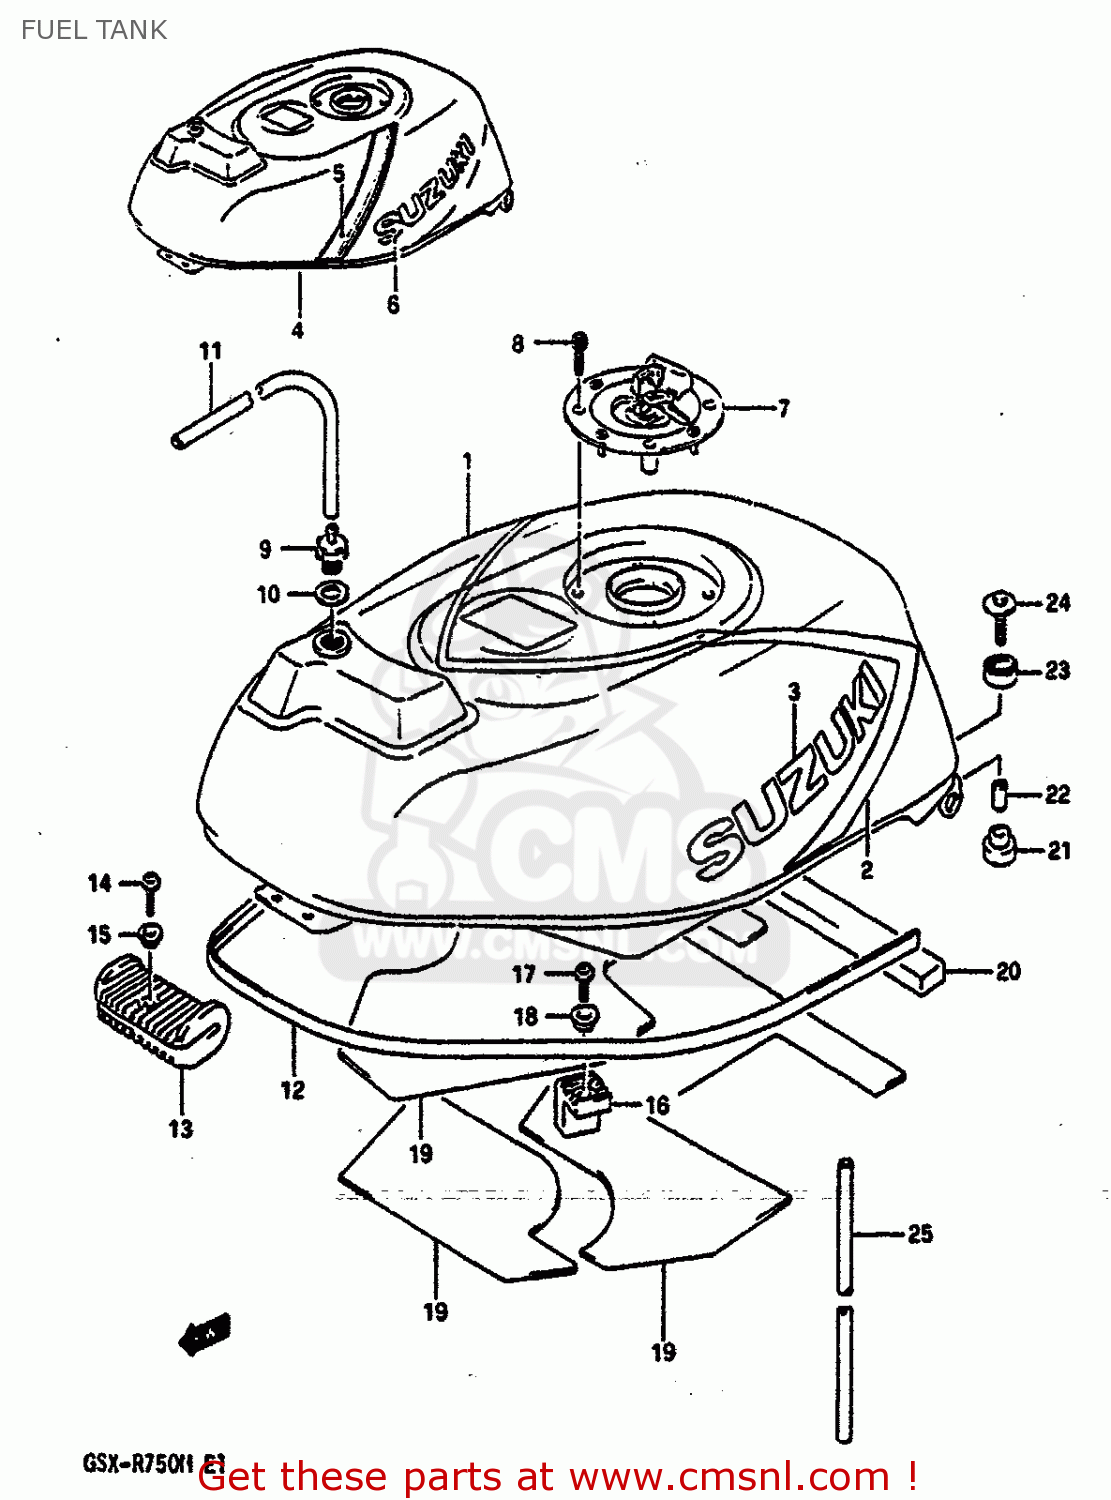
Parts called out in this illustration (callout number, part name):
1	TANK ASSY,FUEL
2	TAPE,FUEL TANK
3	EMBLEM,FUEL TANK(WHITE)
4	TANK ASSY,FUEL
5	TAPE SET,F.T.S
6	EMBLEM,FUEL TANK
7	CAP SET,FUEL TANK
8	BOLT(5X20)
9	PLUG,FUEL TANK BREATHER
10	GASKET(12.5X20X2.5) (NAS)
11	HOSE(5X8.2X600)
12	MOLDING,FUEL TANK
13	CUSHION,FUEL TANK FR
14	SCREW 5X10
15	WASHER
16	CUSHION,FUEL TANK SIDE
17	SCREW
18	WASHER
19	SHIELD,FUEL TANK HEAT
20	CUSHION, AIR SEAL
21	CUSHION
22	SPACER
23	CUSHION
24	BOLT(6X35)
25	HOSE
